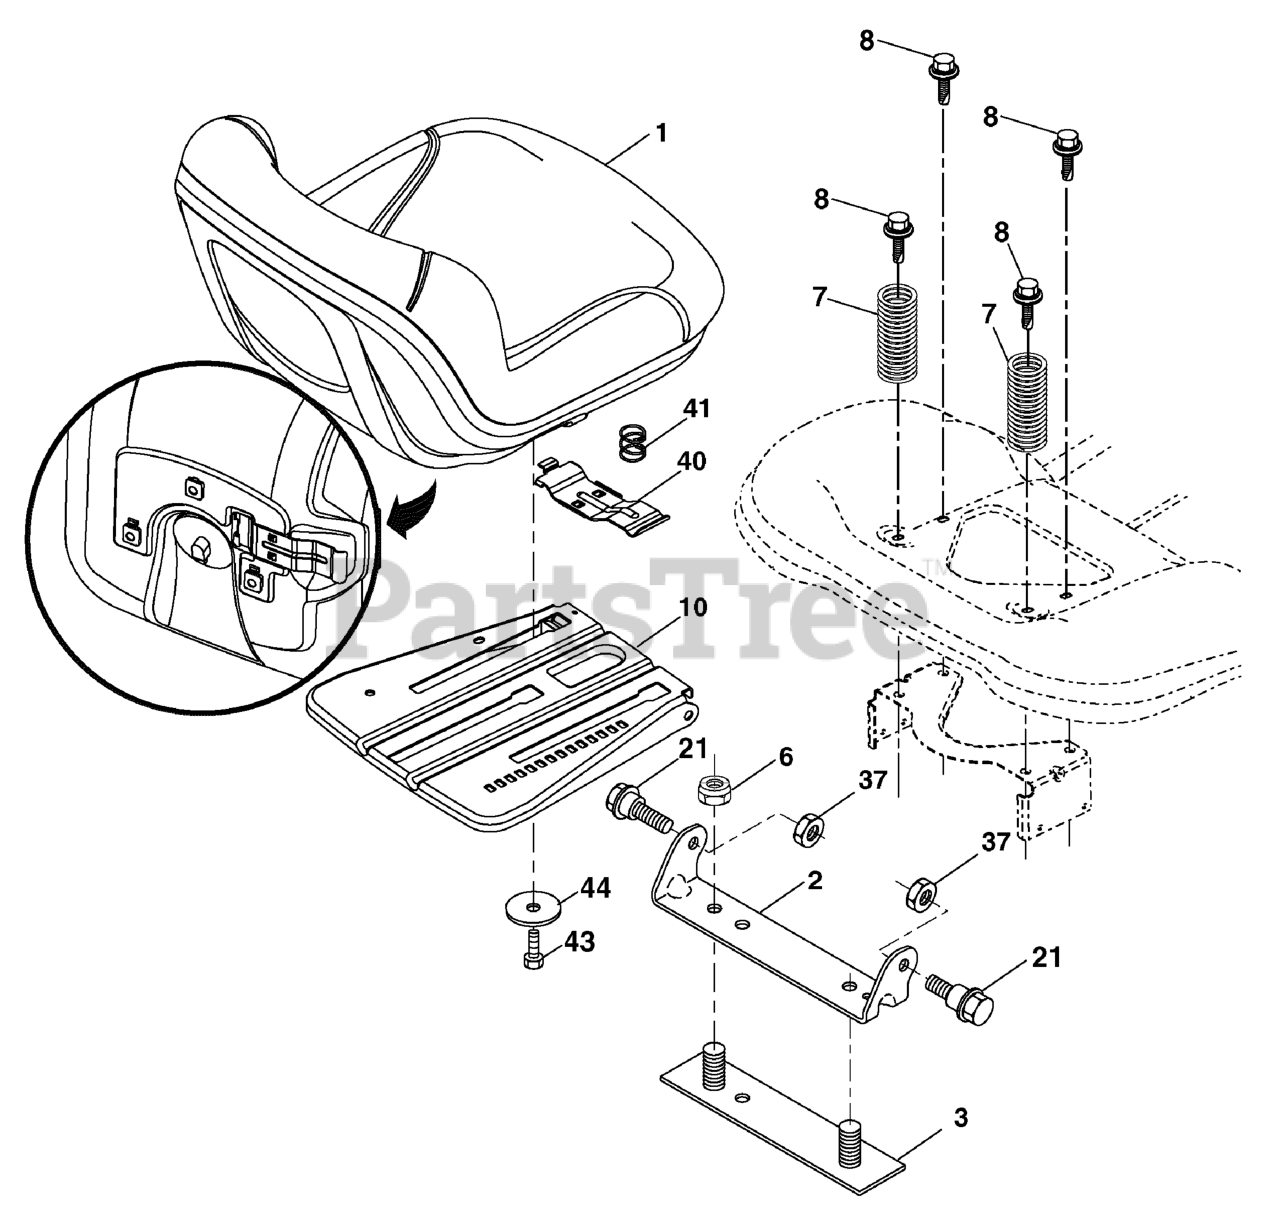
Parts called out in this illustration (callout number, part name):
2	Bracket Pivot Fender
3	Strap, Asm Fender
6	Nut, Lock w/Ins. 3/8-16 unc
7	Spring, Seat Cprsn
8	Bolt 5/16-18 unc x 3/4 w/Sems
10	Pan, Seat
21	Bolt, Shoulder 5/16-18
37	Nut, Lock 5/16-18 unc
40	Handle Slide
41	Spring Latch
43	Bolt 3/8-16 unc x 3/4
44	Washer 13/32 x 2 3/8 x 12 Ga.
